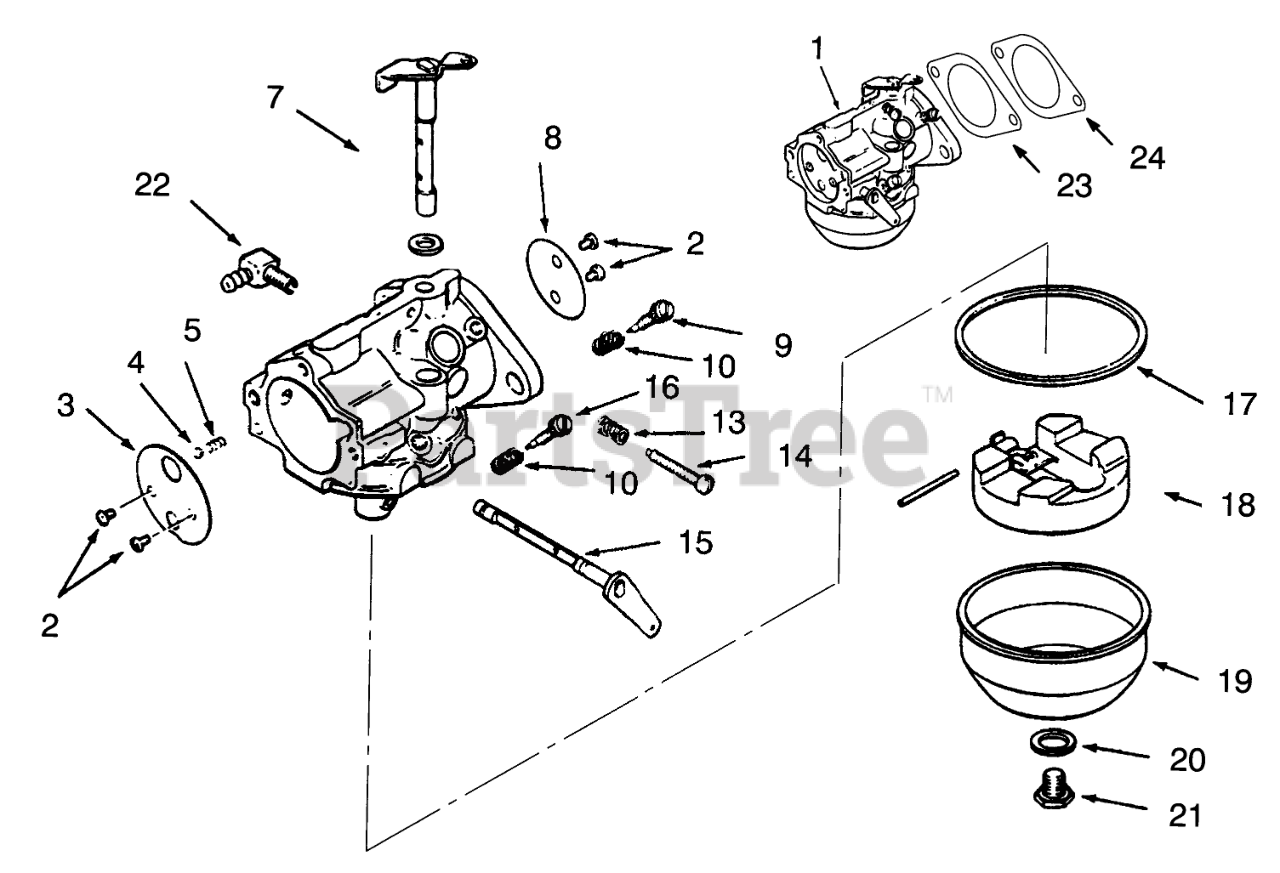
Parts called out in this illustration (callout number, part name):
1	Carburetor Assembly (Incl. Ref. #2-24)
2	Screw
3	Plate-Choke
5	Spring
7	Shaft w/Lever & Seal
8	Plate-Throttle
9	Idle Fuel Adj. Needle
10	Spacer
13	Adj. Spring
14	Idle Speed Adj. Screw
15	Choke Shaft
16	Main-Needle
17	Gasket
18	Kit-Float (Incl. Pin)
19	Bowl-Fuel
20	Gasket
21	Screw
22	Connector 90
23	Gasket
24	Gasket
